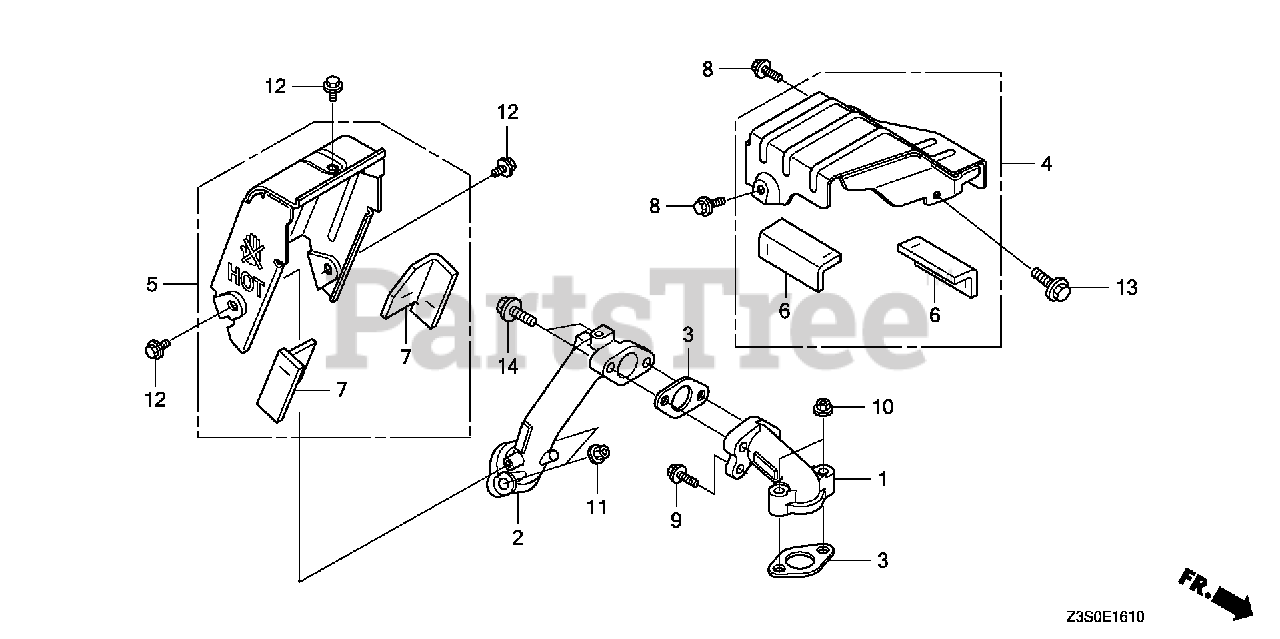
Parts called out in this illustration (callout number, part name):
1	PIPE A, EX.
2	PIPE B, EX.
3	GASKET, MUFFLER
4	COVER ASSY., EX. PIPE
5	PROTECTOR ASSY., EX. PIPE
6	WOOL A, GLASS
7	WOOL B, GLASS
8	BOLT, FLANGE (6X14) (CT200)
9	BOLT, FLANGE (6X20) (CT200)
10	NUT, FLANGE (8MM)
11	NUT, FLANGE (8MM)
12	BOLT, FLANGE (6X8)
13	BOLT, FLANGE (8X18)
14	BOLT, FLANGE (8X35)
